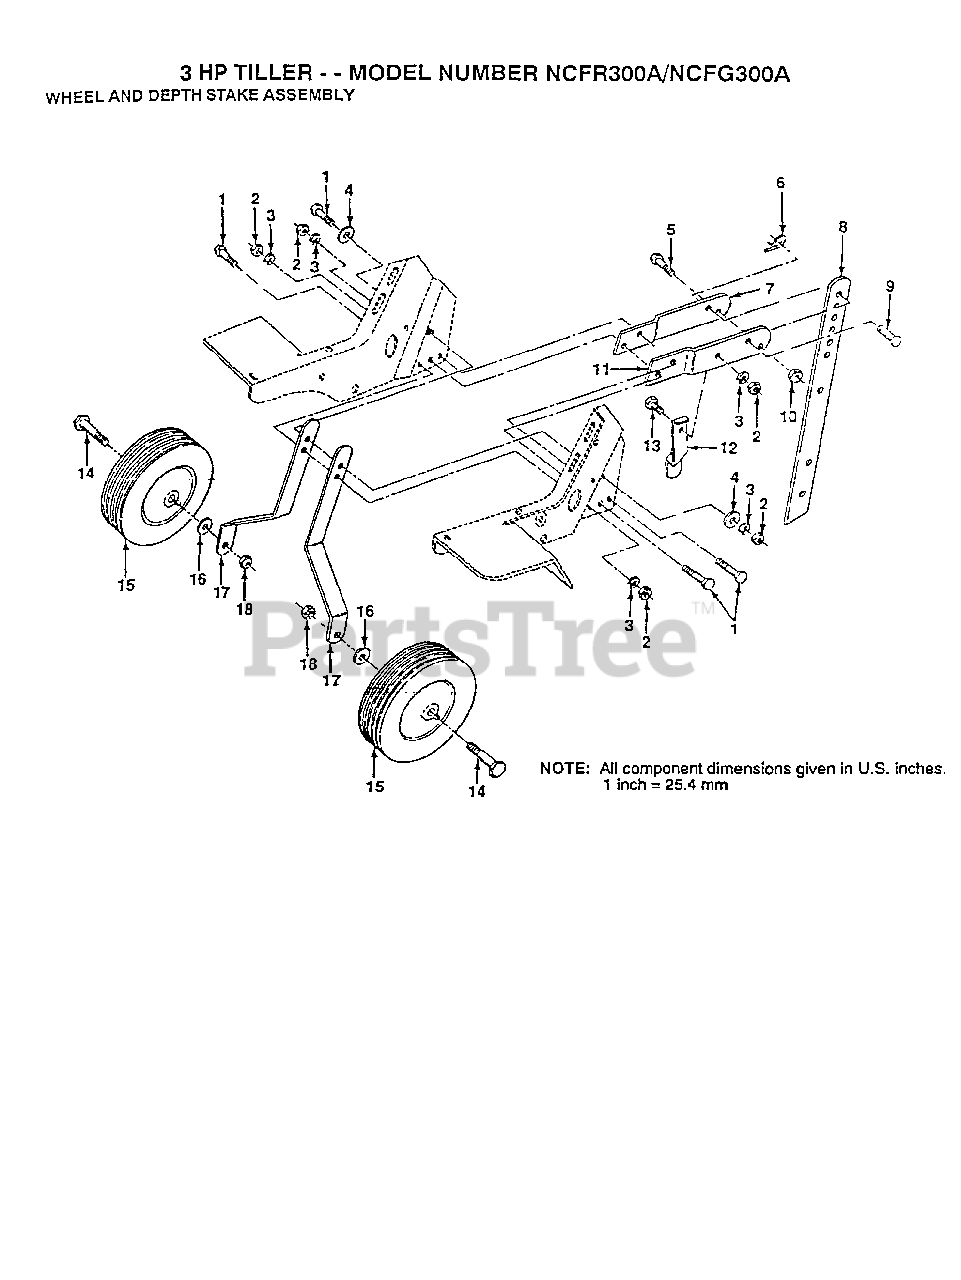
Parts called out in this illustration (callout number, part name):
2	NUT.HEX.5/16-18
3	LOCKWASHER
4	WASHER
5	BOLT.3/8-24X1-1/2
6	SPRING.RETAINER
7	STAKE.SUPT.TILLER
9	DRILLED RIVET RT
10	GRIPCO NUT
12	STAKE SPRING CT
13	BOLT
14	BOLT SHOULDER
16	WASHER
